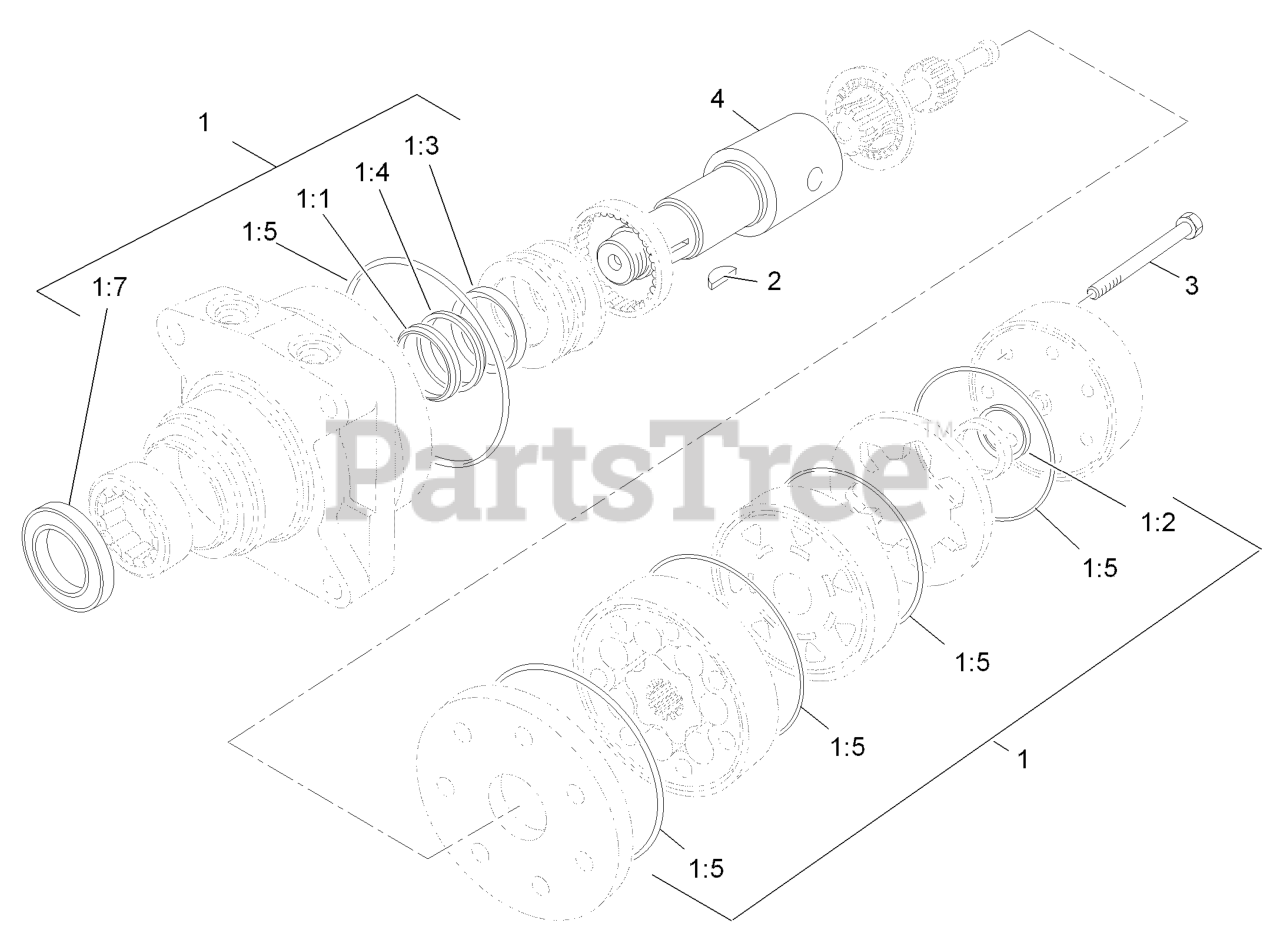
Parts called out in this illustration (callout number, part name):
1	SEAL KIT
1:1	Ring-Back Up
1:2	Seal-Commutator
1:3	Seal-Shaft (Viton)
1:4	Washer-Back Up, Steel
1:5	Ring-Seal (Viton)
1:7	Seal-Dirt And Water
2	KEY-WOODRUFF
3	BOLT-SPECIAL
4	SHAFT-COUPLING
